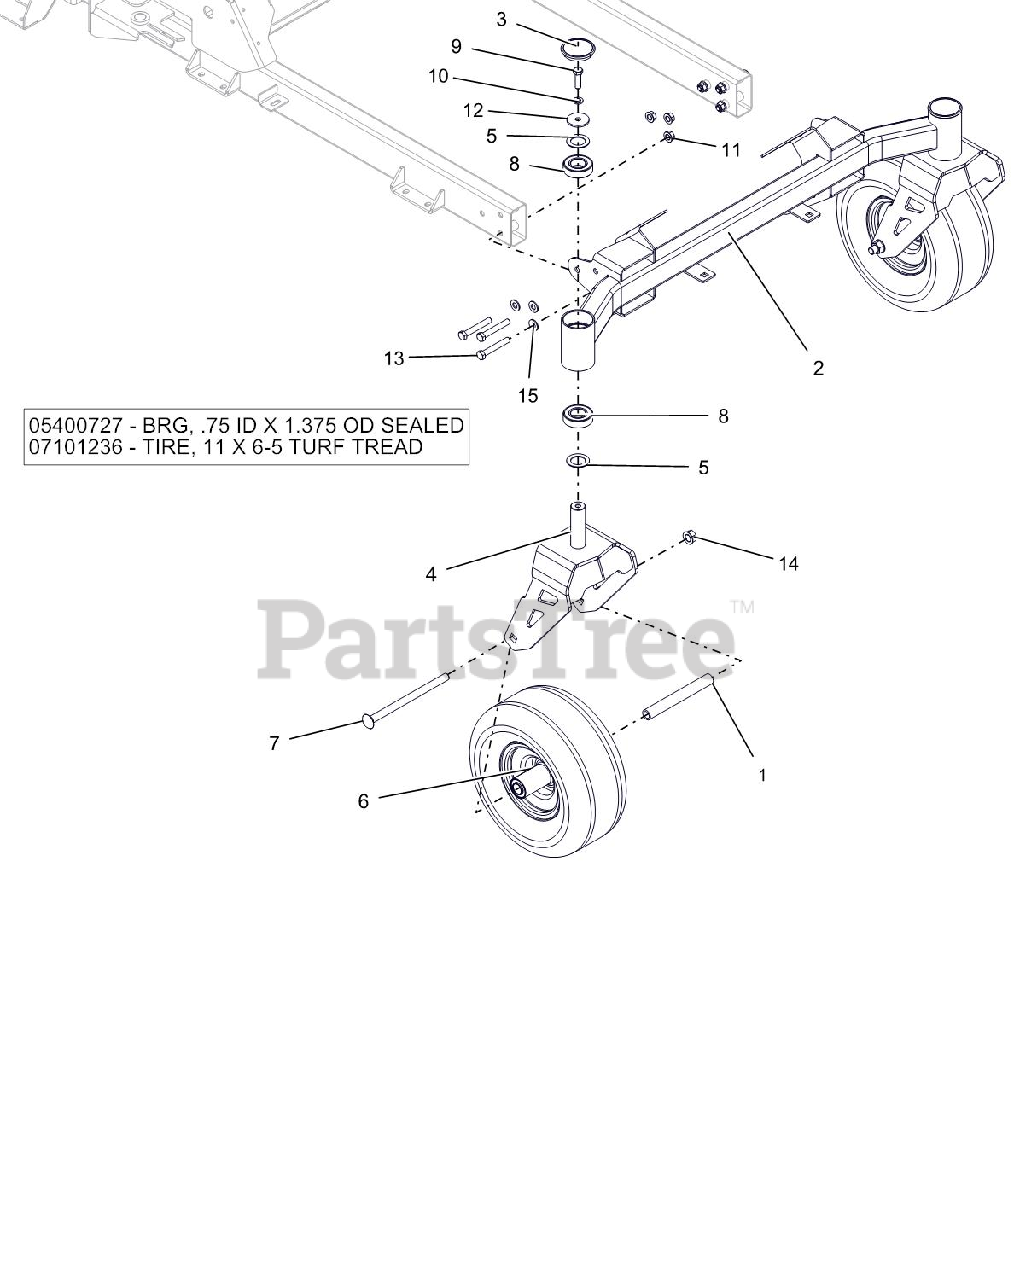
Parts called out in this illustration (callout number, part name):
1	SPACER, FRONT WHEEL (WIDE 6.0)
2	WLDMT, AXLE FRONT
3	CAP, DUST
4	WLDMT, CASTER FORK (WIDE)
5	WSHR-HRD-THRS 1.007X1.542X.062
6	TIRE/WHEEL ASSY, 11X6-5
6	BRG, .75 ID X 1.375 OD SEALED
6	TIRE, 11X6-5 TURF TREAD
7	@BLT-RDHDSQNK .50-13X7.50 G5YZ
8	BRG,BALL 1.00X2.00X.563(1641)
9	@BLT-HEX .38-16X1.25 GR5 YWZC
10	@WSHR-LK .38X.094 REG YWZC
11	NUT-LK-TOP-FLG .38-16 GRG YWZC
12	WSHR-FL-STL .380X1.50X.125YWZC
13	BLT-HEX .38-16X2.50 GR8 YWZC
14	@NUT-LK-TOP-FLG .50-13 YWZC
15	WSHR-HDND .406X.812X.055
